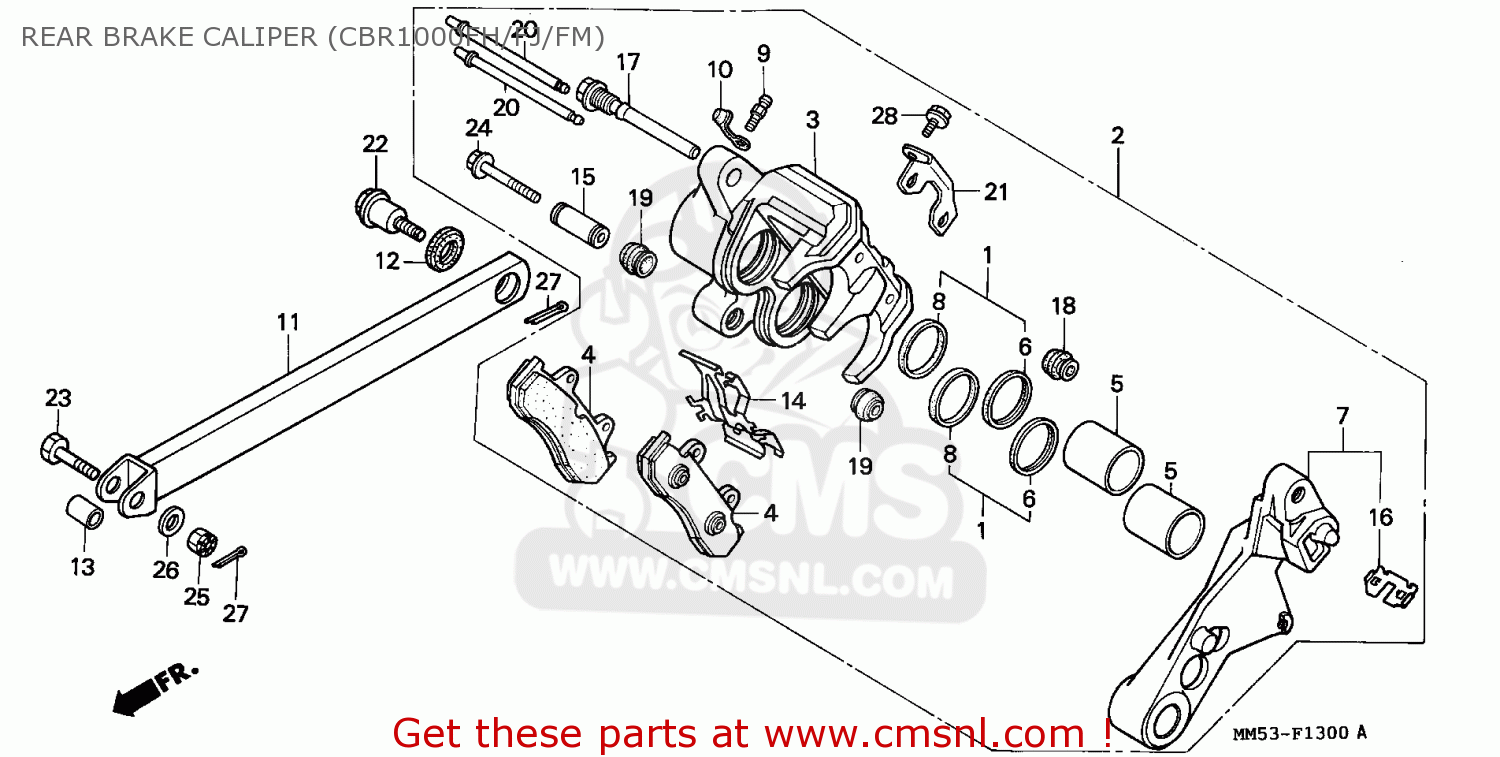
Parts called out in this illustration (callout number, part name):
2	CALIPER ASSY,RR
3	CALIPER COMP.,RR.
4	PAD COMP.,RR.(NIS (MCA)
5	PISTON
6	DUST SEAL
7	BRACKET COMP.,RR.
8	SEAL,PISTON
9	SCREW, BLEEDER
10	CAP,BLEEDER
11	ARM,COMP.,RR.BRK.
12	WASHER, TORQUE
13	COLLAR,LINK
14	SPRING,PAD
15	SLEEVE
16	BRACKET RETAINER
17	PIN,BOLT
18	BOOT B
19	BOOT,PIN
20	PIN,HANGER
21	PLATE
22	BOLT,TORQUE LINK
23	BOLT,STOPPER ARM
24	BOLT,FLANGE 8X49
25	NUT,CASTLE,8MM
26	WASHER,PLAIN,8MM
27	PIN,SPLIT, 2.5
28	BOLT,FLANGE,6X10
